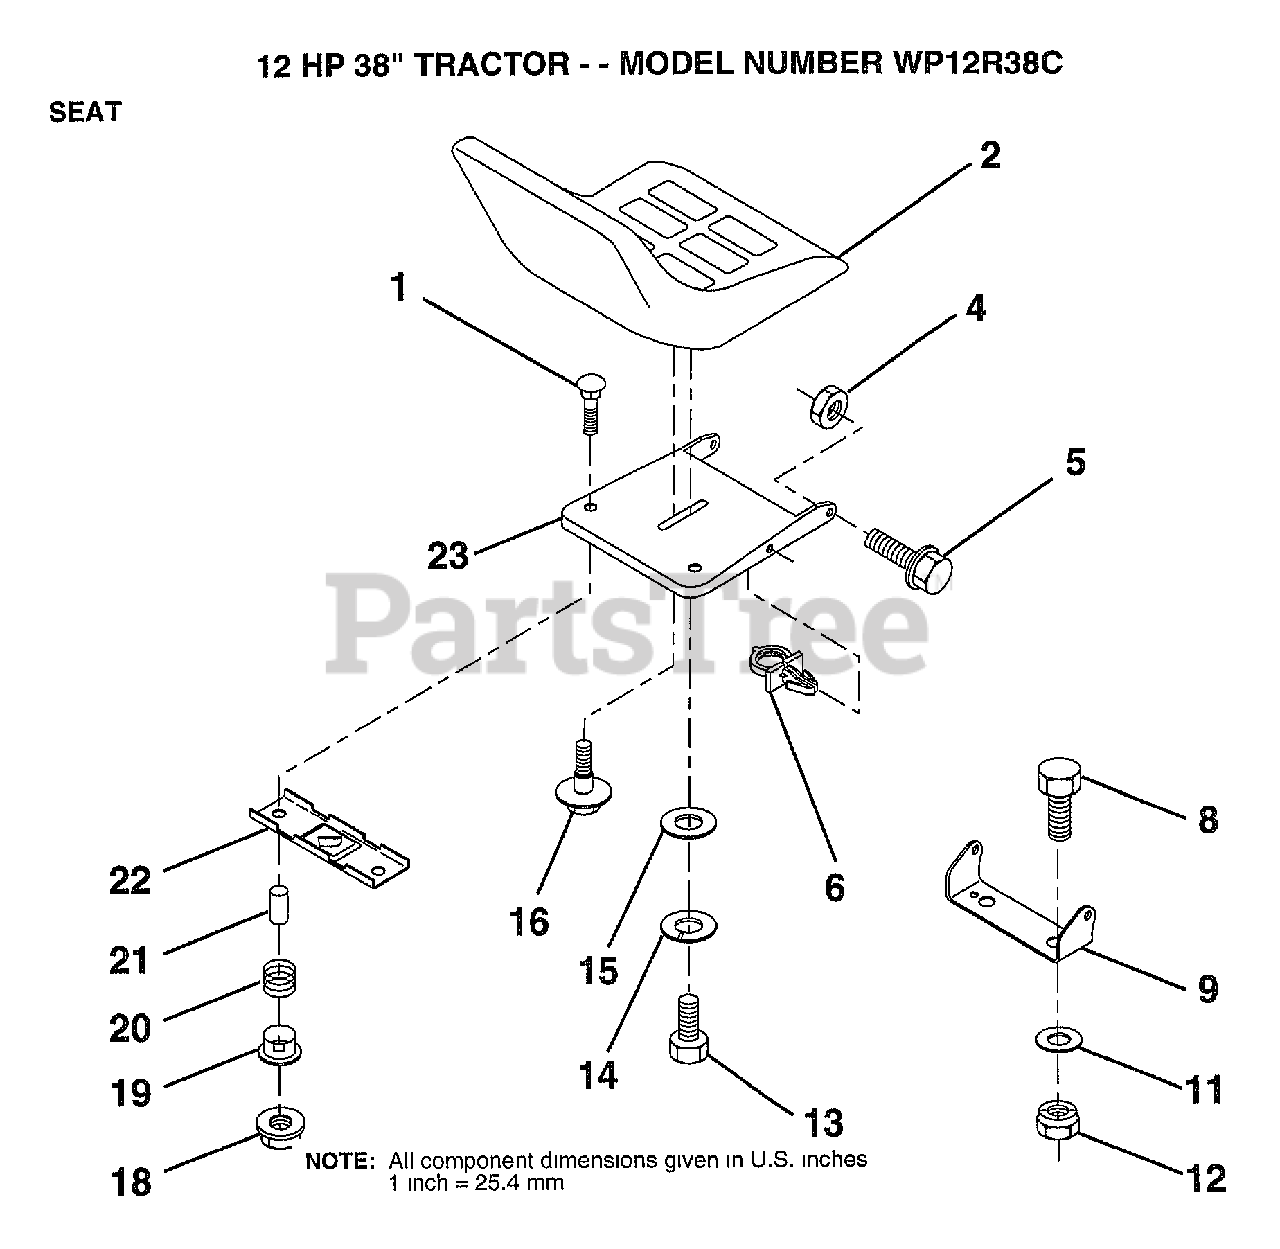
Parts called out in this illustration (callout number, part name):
4	NUT
5	BOLT.SHLD.5/16-18
6	CLIP PUSH - IN
8	BOLT
9	BRACKET PVT SEAT
11	WASHER
12	NUT
13	BOLT
14	LOCKWASHER
15	WASHER
16	"BOLT,SHOULDER"
19	BUSHING
20	SPRING
21	SPLIT SPACER
22	BRKT SWITCH
